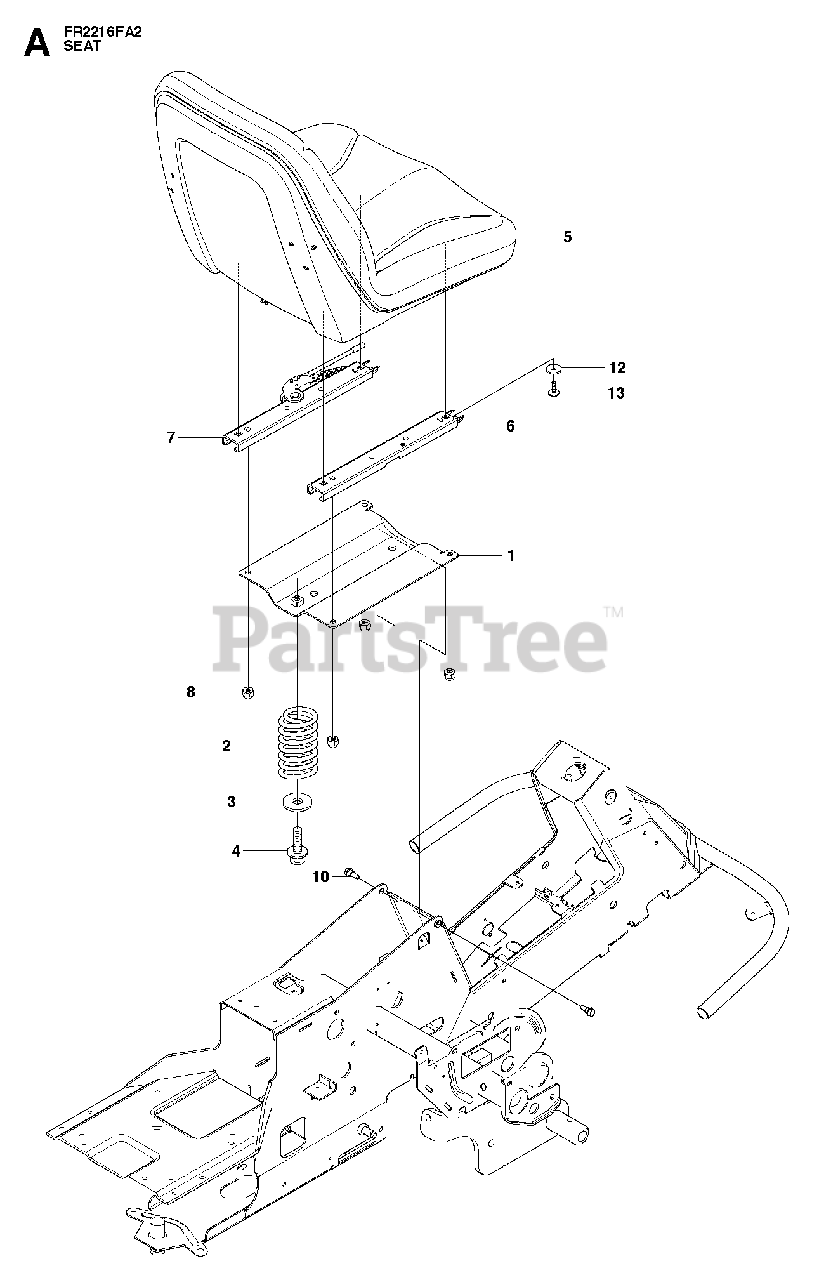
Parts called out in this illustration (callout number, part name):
2	SEAT SPRING
4	SCREW M10X25
8	LOCKNUT M8
12	WASHER
13	BOLT
